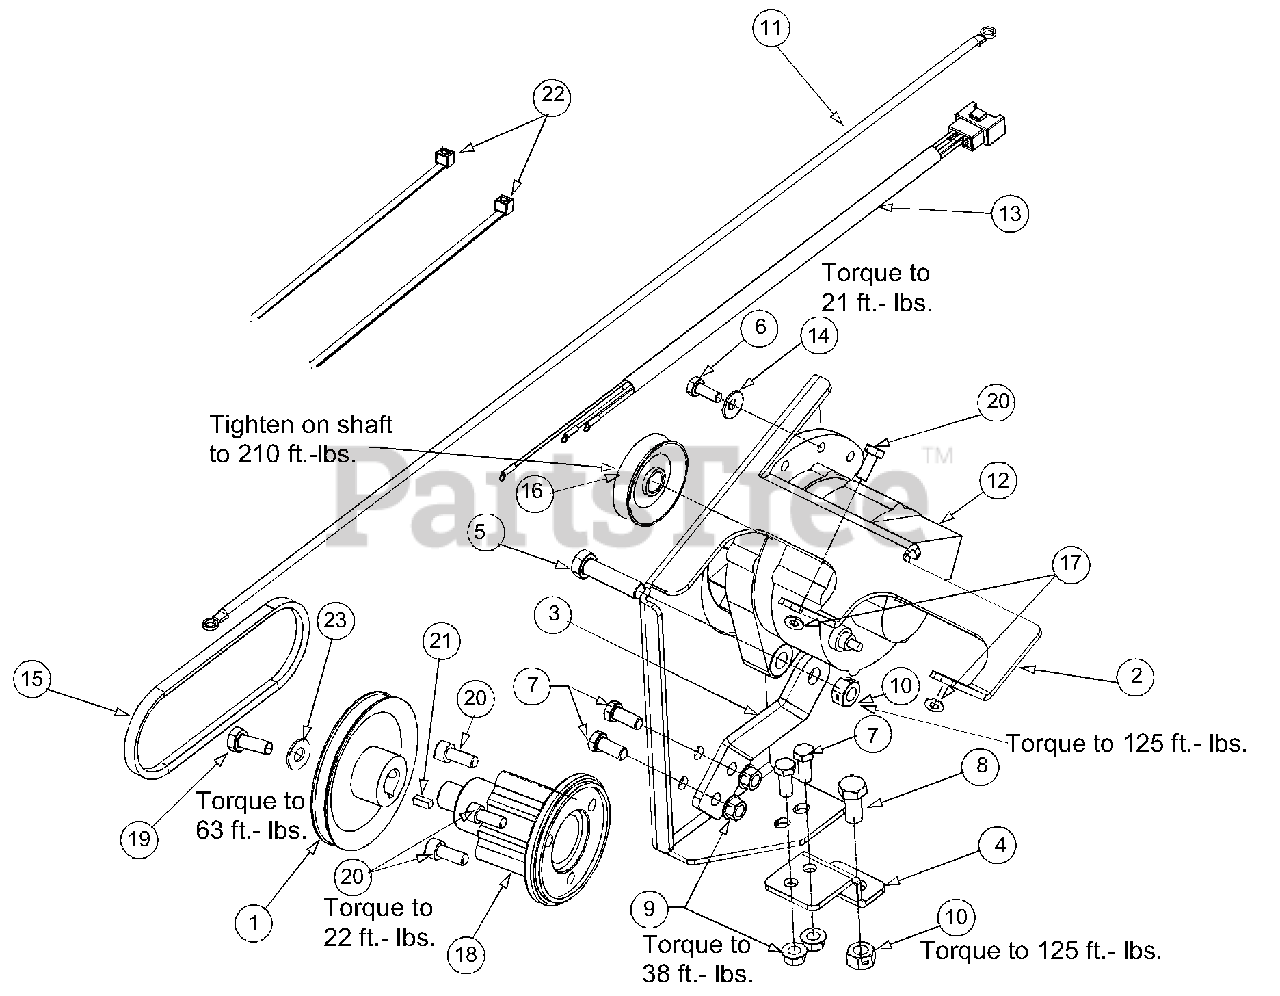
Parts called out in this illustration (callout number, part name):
1	Alternator Pulley Assembly
6	Screw, 5/16-18 x 1.00
7	Hex Screw, 3/8-16 x.880, GR5
8	Hex Screw, 1/2-13 GR8
9	Flange Lock Nut, 3/8-16
10	Hex Lock Nut, 1/2-13
11	Alternator Output Harness
12	65 Amp Auxiliary Alternator
13	Regulator Harness
14	Bell Washer,.340 x.872 x.060
15	V-Belt 3/8 x 35.68 LG
16	Pulley, 2.65 OD
17	Flat Washer,.330 x.687 x.030
20	Screw, M8 x 1.25 x 25mm Lg.
21	Square Key, 3/16 x.50
22	Cable Tie
23	Flat Washer,.406 x1.25 x.157
